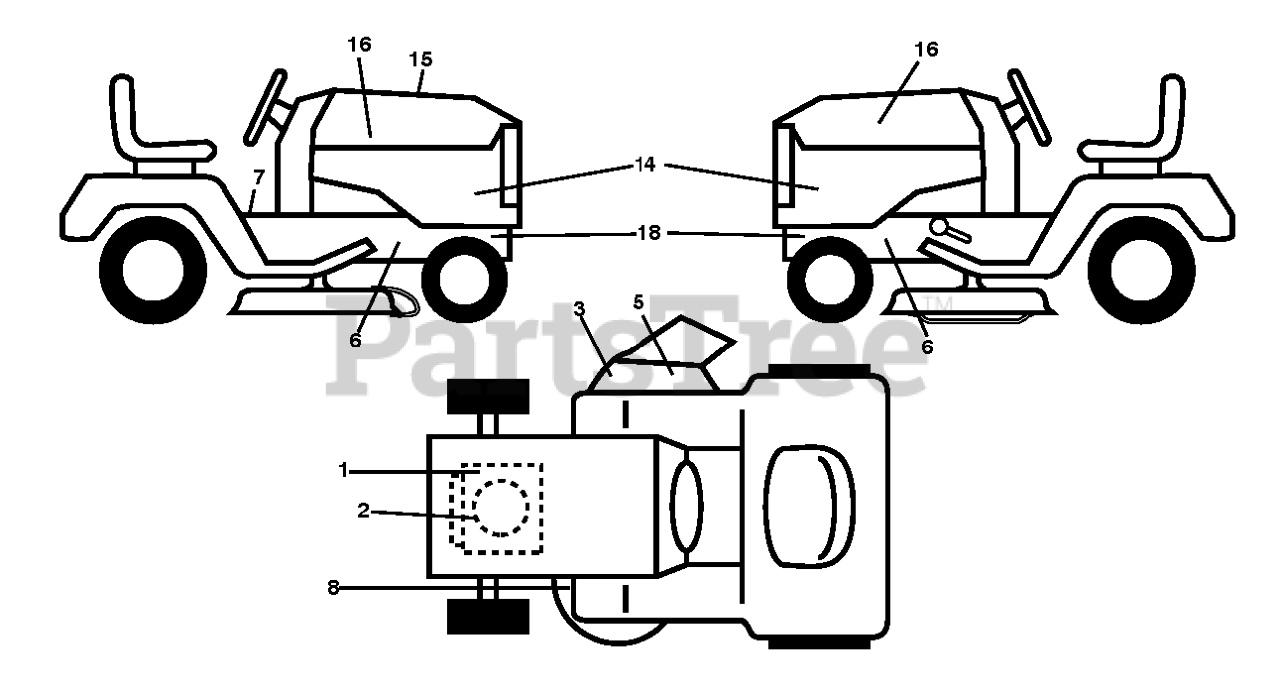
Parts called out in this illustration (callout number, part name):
1	DECAL.ENGINE.WARNING
2	DECAL ENG.DECAL.B&S.ENDURANCE.
3	DECAL.DFLCTR.WARNNG.CTFNGR.SYM
5	DECAL, DECK DEFLECTOR, WARNING
6	DECAL.WARNING.SERVCE/FIRE
7	DECAL.TRACTOR.SADDLE
8	DECAL.V-BELT.SCH.42/46"MEC/ELE
14	DECAL.SDPNL.TS346.SET
15	DECAL DECAL.RPL.BSM44.END.TLW.
16	DECAL.WB.178MM.15.HUSQ.NEWBRAN
18	DECAL.CHASSIS.HOT.MUFFLER
